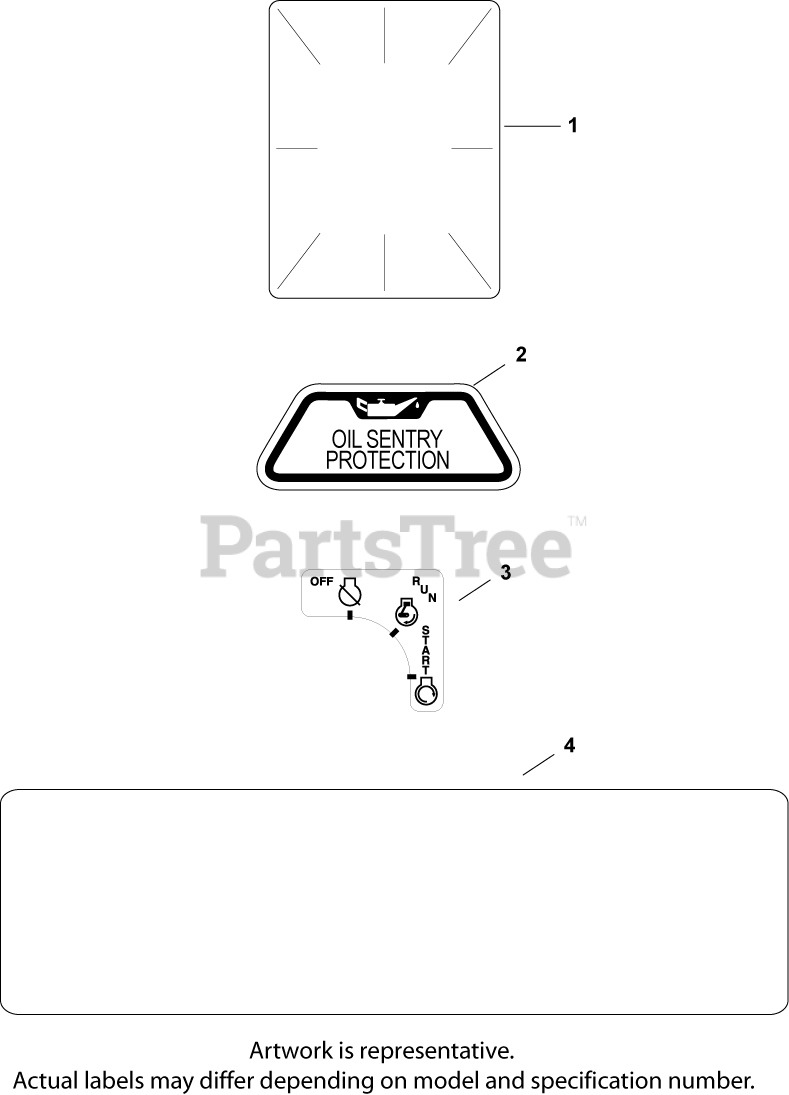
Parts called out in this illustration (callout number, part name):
1	DECAL, CLEAR LAMINATE USE 25 113 70-S
2	DECAL, OIL SENTRY - (#DSC)
3	DECAL, KEY SWITCH
4	DECAL, 27 HP
